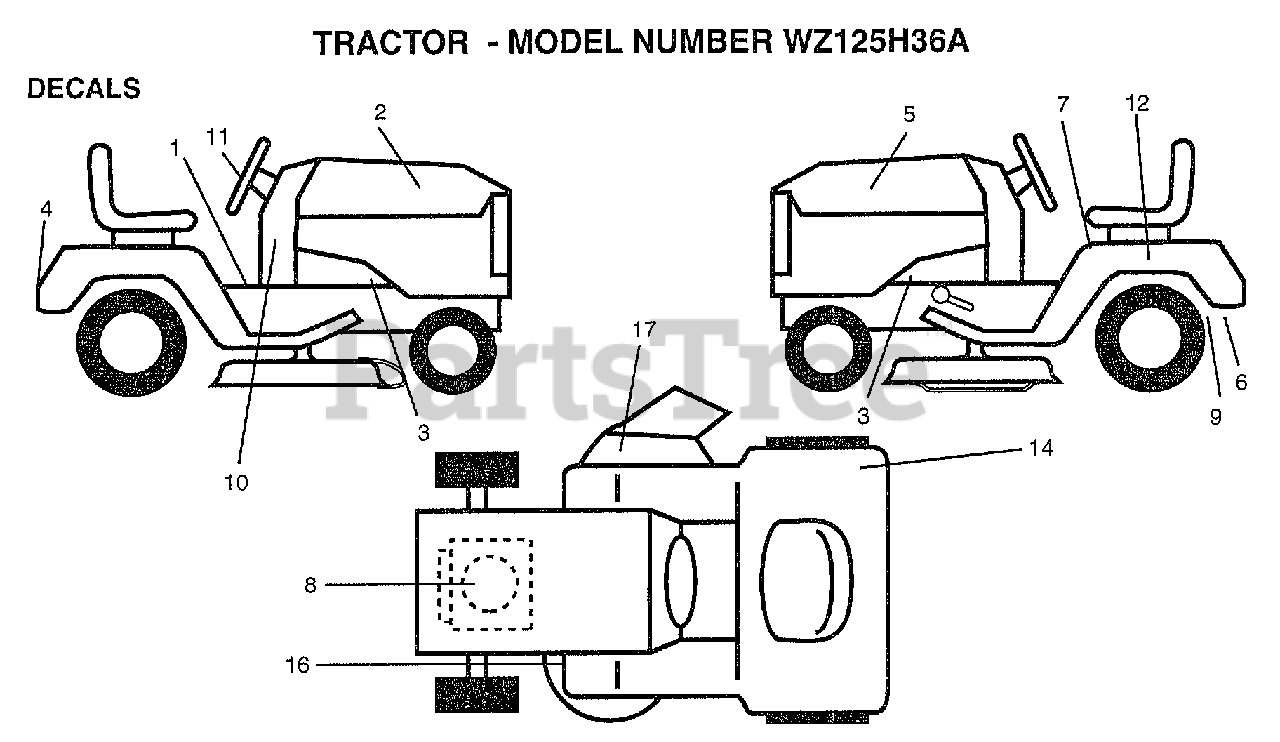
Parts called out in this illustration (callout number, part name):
1	DECAL CLUTCH/BRAK
2	DECAL.HOOD.RH
3	"DECAL CHASSIS,HOT"
4	DECAL.FENDER
5	DECAL.HOOD.LH
6	DECAL.DRAWBAR.CTL
7	DECAL.READ.O.MANU
8	DECAL, HP ENGINE
9	DECAL.DRAWBAR.LDL
10	DECAL.EURO.ST.CE.
11	DECAL.INS.STRG/WH
12	DECAL.BATRY.3-3908
16	DECAL.DANGER.CUTF
17	DECAL.V.BELT
